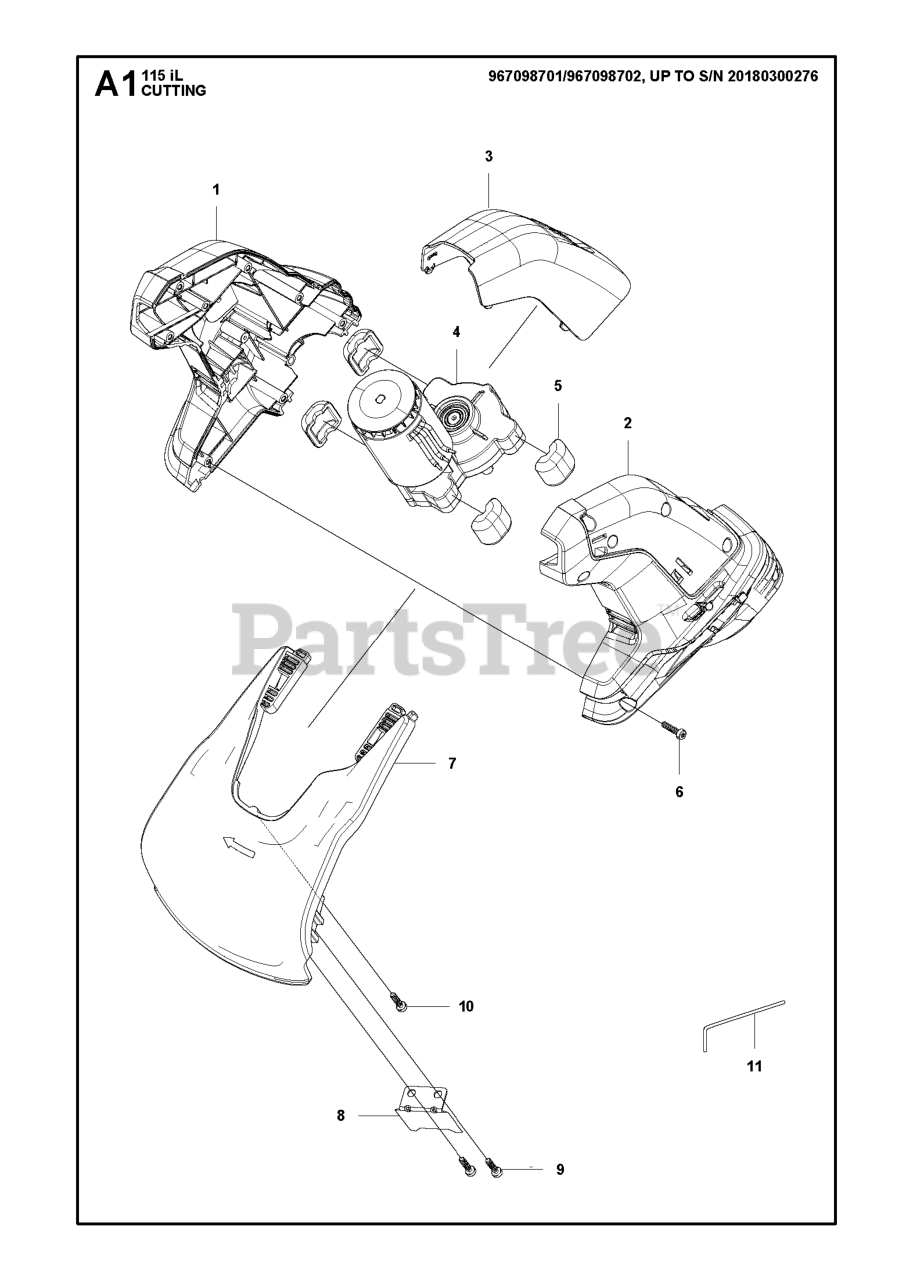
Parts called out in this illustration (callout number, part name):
1	HOUSING MOTOR HOUSING L 36V
2	HOUSING MOTOR HOUSING R 36V
3	COVER MOTOR HOUSING
4	GEARBOX ASSY 36V
6	SCREW ST4X16
7	GUARD FOR CUTTING HEAD 36V
8	BLADE LINE CUTTER
10	SCREW ST4*16
